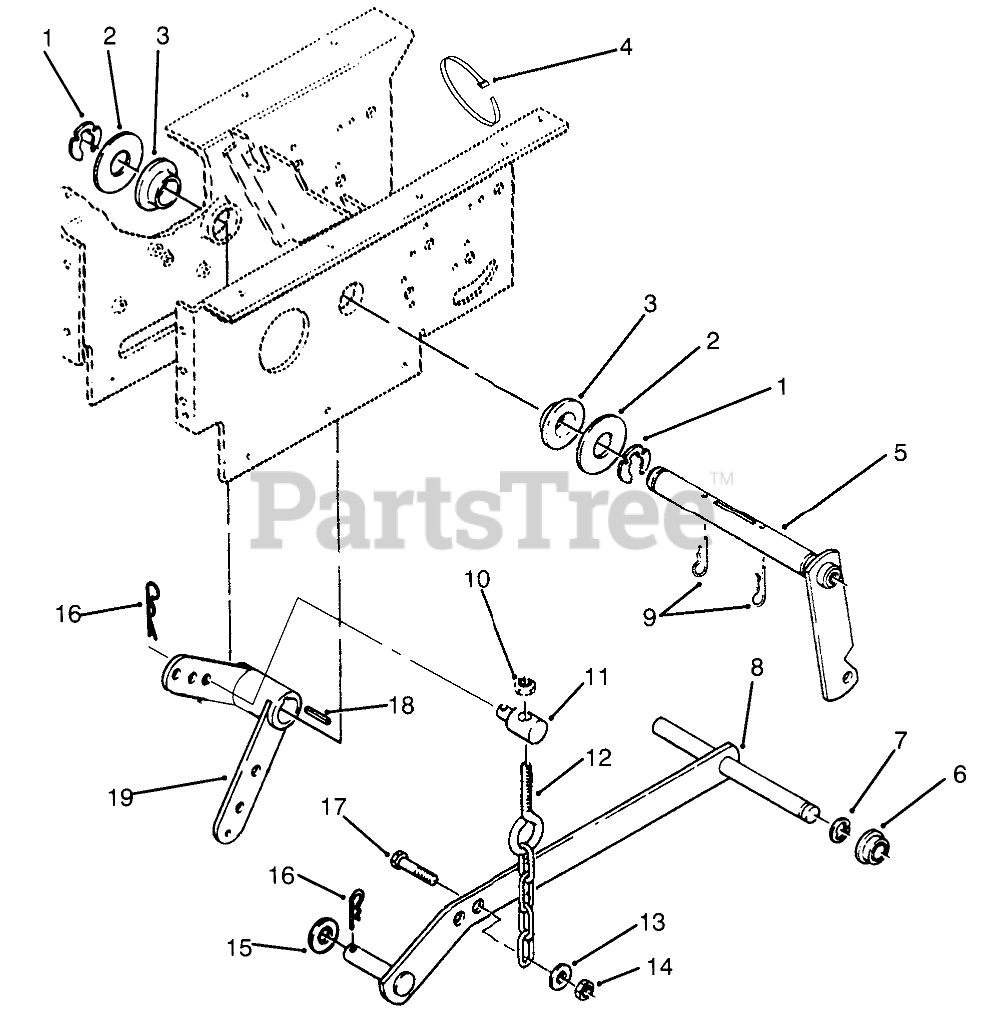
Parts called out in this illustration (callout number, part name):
1	RING-RETAINING
2	WASHER-FLAT
3	BEARING-FLANGE
4	TIE-CABLE
5	WLDMT-LIFT ARM
6	BUSHING
7	RING-RETAINING, EXTERNAL
8	Bar-Lift
9	Pin-Cotter
10	NUT-LOCK, NI
11	TRUNNION-LIFT
12	CHAIN-LIFT
13	WASHER-PLAIN
14	NUT-LOCK, NI
15	WASHER-FLAT
16	Hairpin Cotter
17	SCREW-HH
18	KEY-SQUARE
19	LIFT LEVER ASM
